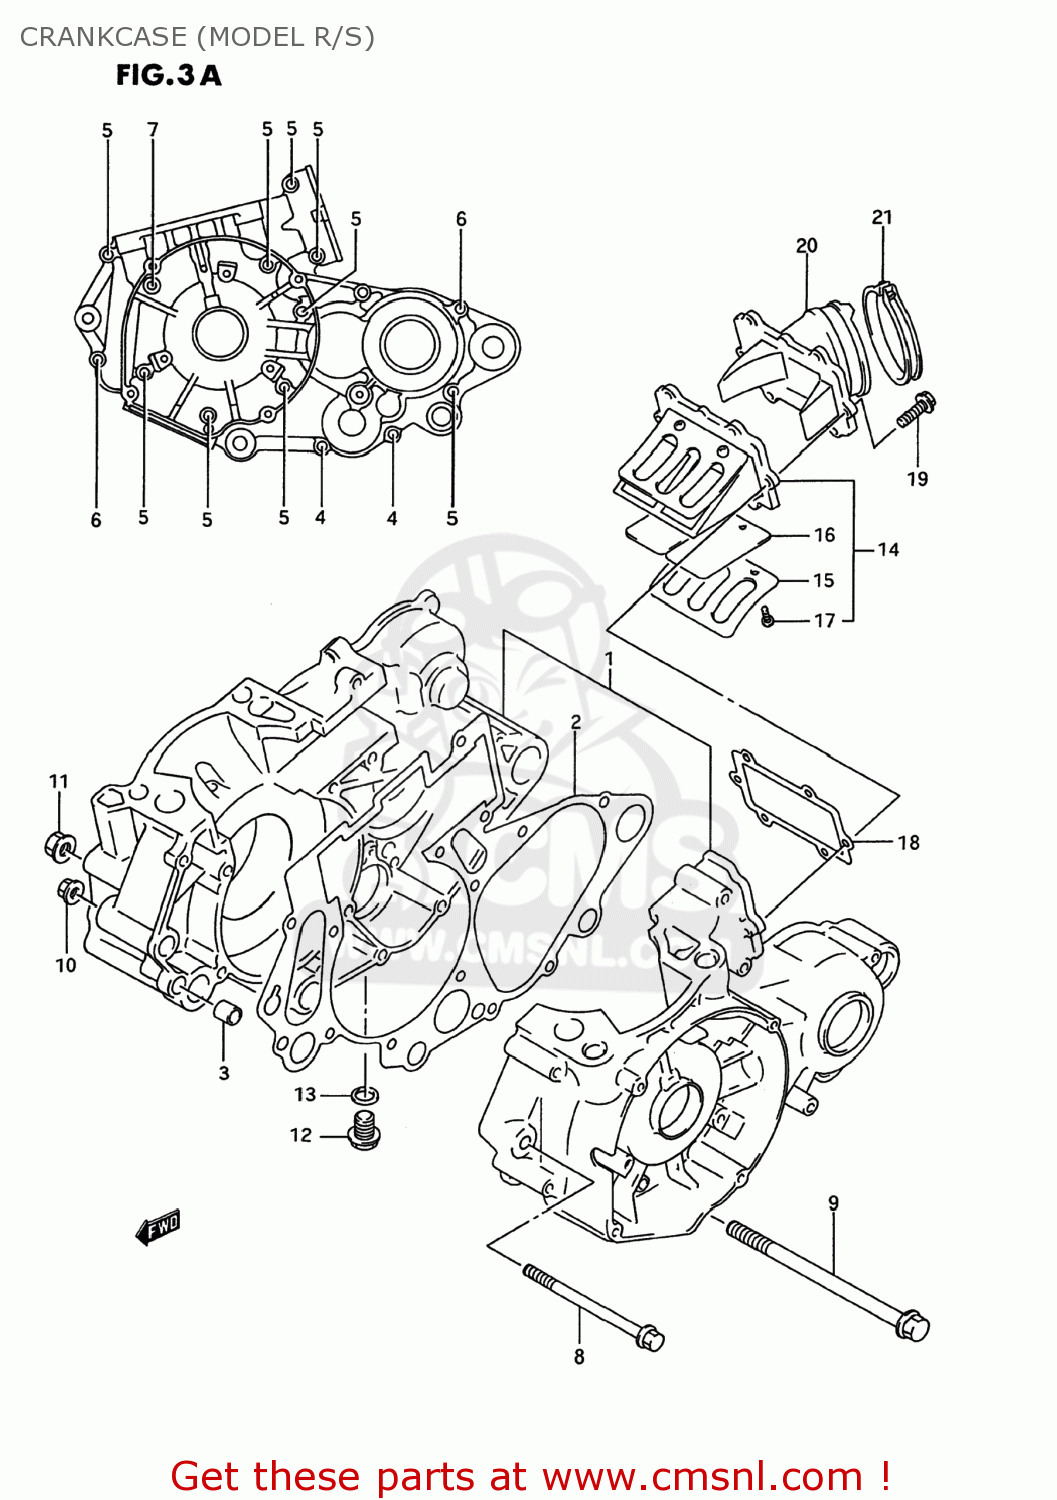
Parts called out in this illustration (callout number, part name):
1	CRANKCASE SET
2	GASKET,CRANKCASE
3	PIN
4	BOLT
5	BOLT
6	BOLT
7	BOLT
8	BOLT(8X102)
9	BOLT(10X140)
10	NUT
11	NUT
12	Bolt
13	GASKET(12.1X16.2X3.7) (NAS)
14	VALVE ASSY,REED
15	STOPPER,REED VALVE
16	VALVE,REED
17	SCREW
18	GASKET,REED VALVE (NAS)
19	SCREW
20	PIPE,INTAKE
21	CLAMP
